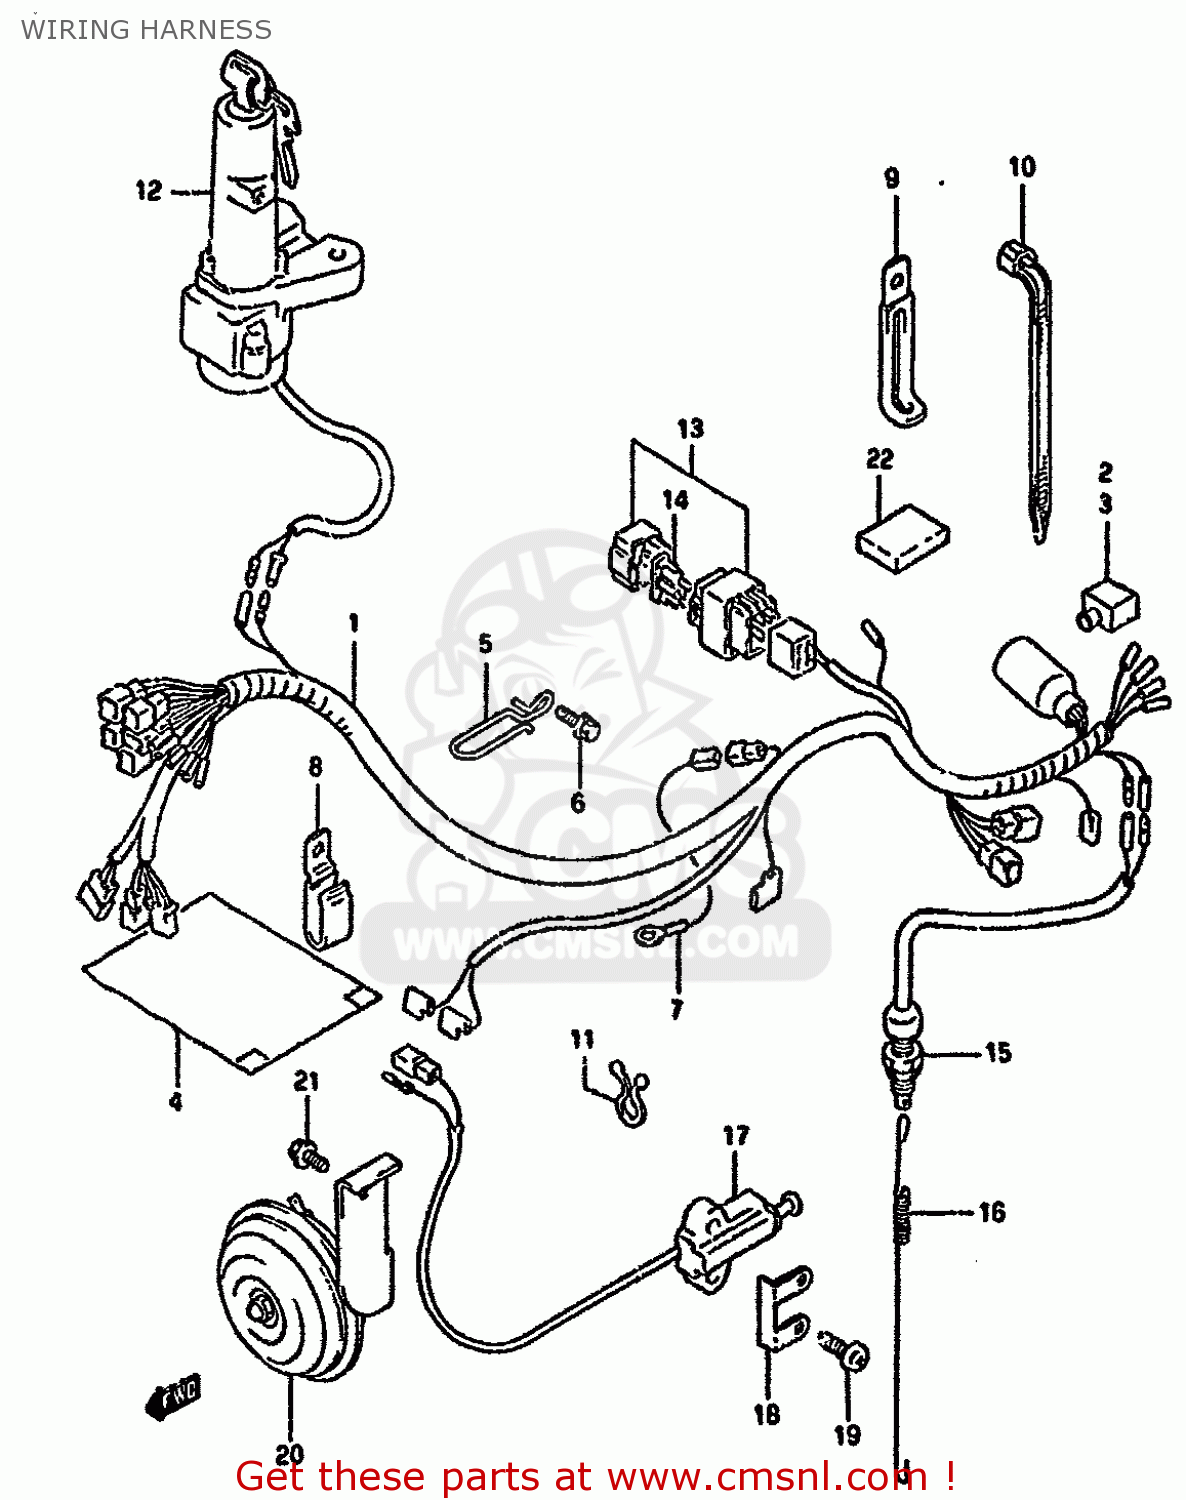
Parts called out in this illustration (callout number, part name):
1	HARNESS,WIRING
2	CAP,BATTERY PLUS TERMINAL
3	CAP,BATTERY PLUS TERMINAL
4	COVER,WIRING HARNESS
5	GUIDE,WIRING HARNESS
6	BOLT
7	WIRE
8	CLAMP
9	CLAMP
10	CLAMP
11	CLIP(ID:11.5)
12	SWITCH ASSEMBLY,IGNITION
13	BOX ASSY,FUSE
14	FUSE(15A)
15	SWITCH ASSY,STOP LAMP
16	SPRING
17	SWITCH ASSEMBLY,SIDE STAND
18	PROTECTOR,SIDE STAND SWITCH
19	SCREW
20	HORN ASSY
21	BOLT
22	PROTECTOR,WIRING HARNESS
